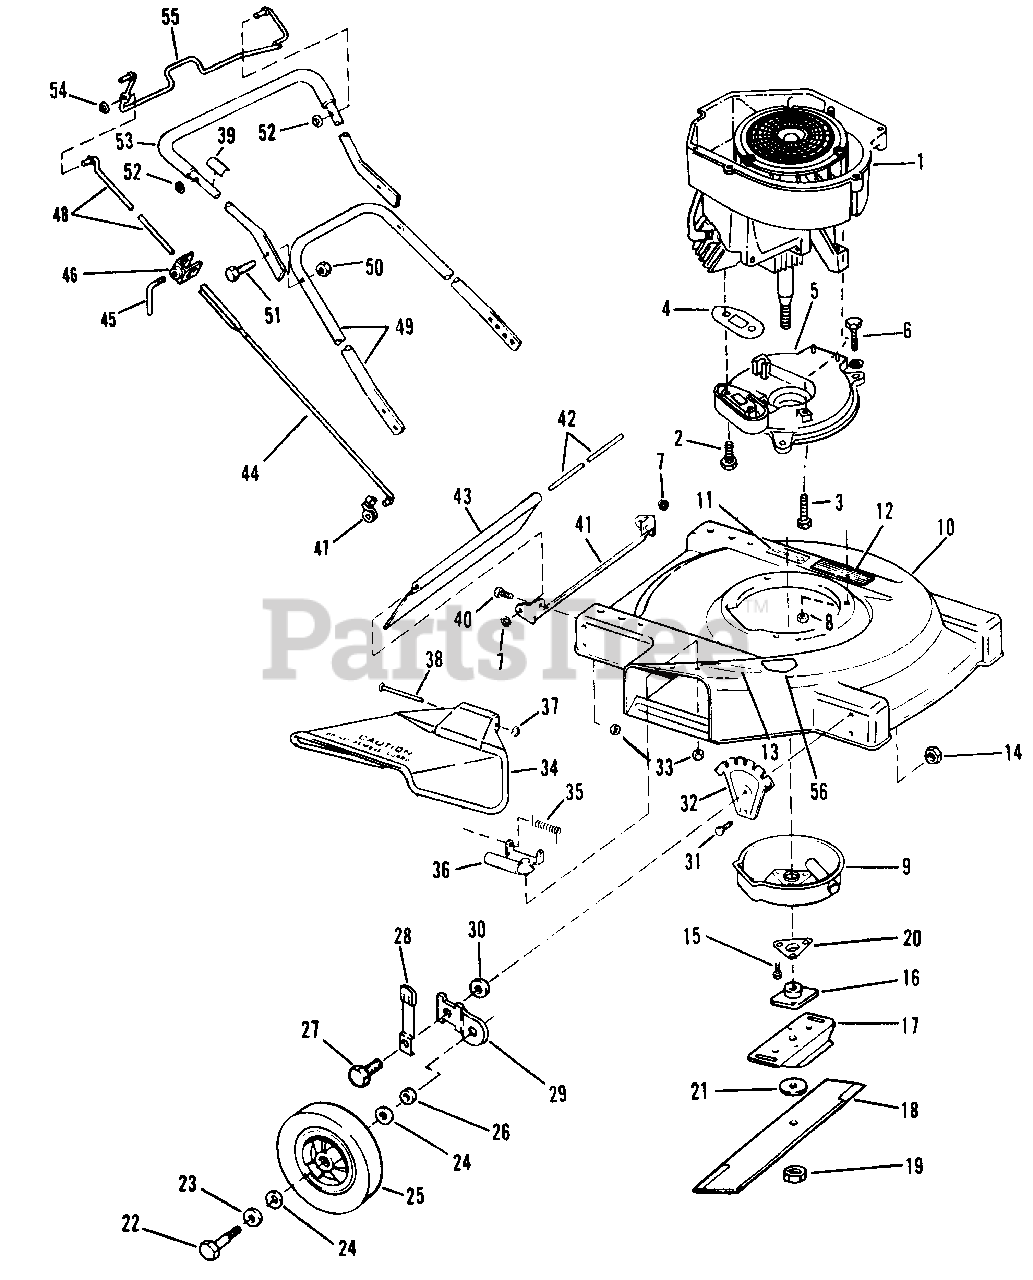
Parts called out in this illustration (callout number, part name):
1	Engine-F340
2	Screw-Muffler Plate to Cylinder
3	Screw-Muffler Plate to Cylinder
4	Gasket
5	Muffler Plate
6	Screw-Muffler Plate to Hsg.
7	Nut
8	Locknut
9	Muffler Cover Ay.
10	Housing Assembly-20"
11	Decal-Starting Pad
12	Pad-Starting
13	Decal-Caution Deflector
14	Nut-Ht. Adj. & Back-up Plate
15	Screw-Muffler Cover to Plate
16	Collar & Plate Assembly
17	Stiffener-Blade
18	Blade-20"
19	Nut-Blade
20	Support-Crankshaft
21	Washer-Blade
22	Bolt-Wheel
23	Washer-Wheel Bolt Head
24	Washer-Felt
25	Wheel & Tire Ay.-Front
26	Washer-Wheel Bolt
27	Bolt-Shoulder
28	Knob & Spring Ay.
29	Height Adj. Brkt.-Front
30	Washer-Height Adjust
31	Screw-Ht. Adj. Brkt. to Hsg.
32	Plate-Ht. Adj. Back-up
33	Nut-Chute Deflector & Trailing Shield
34	Chute Deflector Ay.
35	Spring
36	Hinge & Screw Ay.
37	Nut
38	Pin-Hinge
39	Decal
40	Screw-Trailing Shield
41	Bracket-Trailing Shield
42	Rod-Trailing Shield
43	Trailing Shield
44	Control Rod Assembly
45	Lever
46	Nut
47	Clip
48	Control Rod
49	Handle Section-Bottom
50	Nut Handle
51	Screw-Handle
52	Nut
53	Handle & Grip Ay.
54	Nut
55	Lever-Control
56	Decal-Blade Contact Warning
